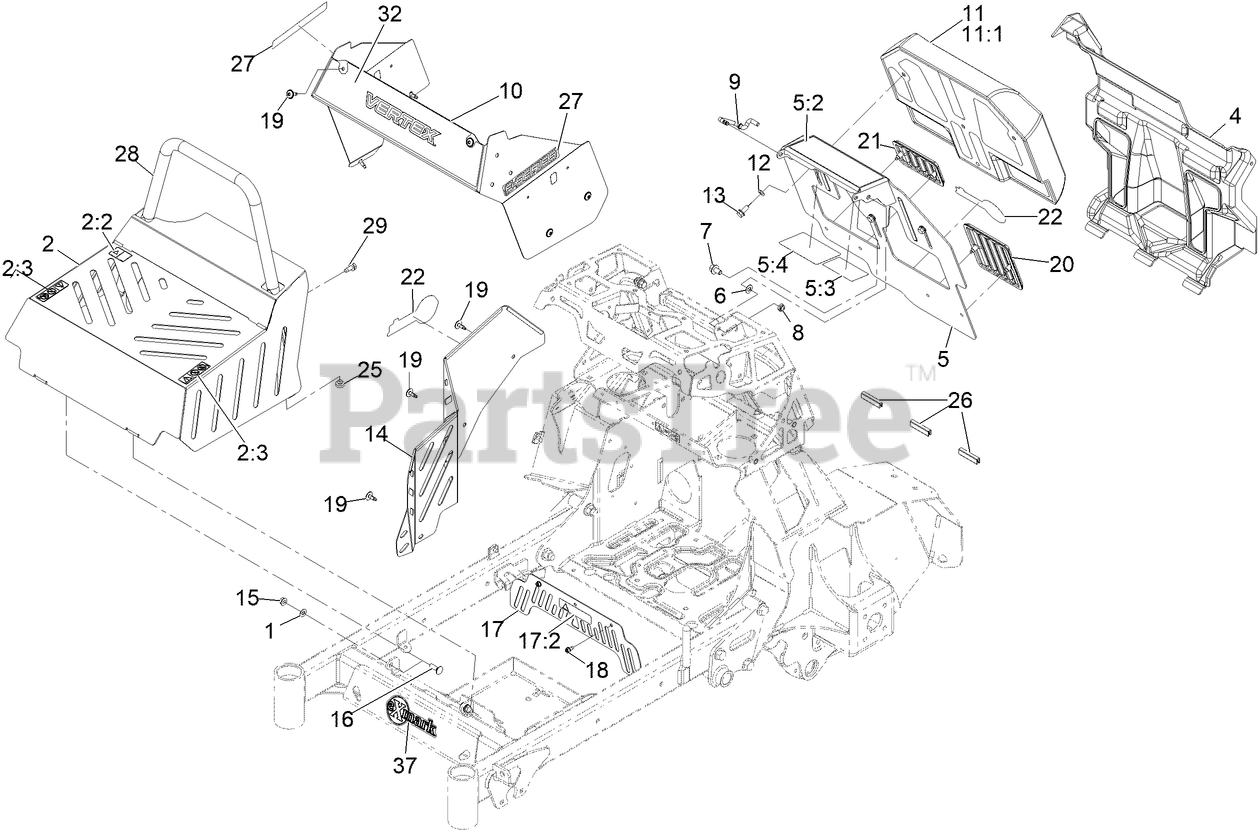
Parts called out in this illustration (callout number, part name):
1	SPACER-NYLON
2	ASM-Cover W/Decals
2:2	DECAL-WARNING
2:3	DECAL-NO STEP/RIDERS
4	COVER-REAR STE
5	ASM, PAD BACKING W/ DECALS
5:2	DECAL-WARNING
5:3	DECAL-DRIVE RELEASE
5:4	DECAL-SERVICE AID SM
6	WASHER-THRUST
7	SCREW-HHF
9	ROD, PROP
10	SKIN TOWER
11	PAD-THIGH
11:1	Cover Pad
12	WASHER-BELLEVILLE
13	SCREW-HHF
14	Cover-Rt Side
16	BOLT-CARR
17	ASM, BELT GUARD W/ DECAL
17:2	DECAL-WARNING
18	SCREW-HWH
19	SCREW, TORX
20	PAD, KNEE, LT
21	PAD, KNEE, RT
22	DECAL-EXMARK LOGO
26	STRIP-SEAL 2.13
27	DECAL-E-SERIES
28	TUBE-GUARD MUFFLER
29	SCREW-THD ROLL, HWH
32	DECAL-FRONT PANEL
37	DECAL-EXMARK LOGO
